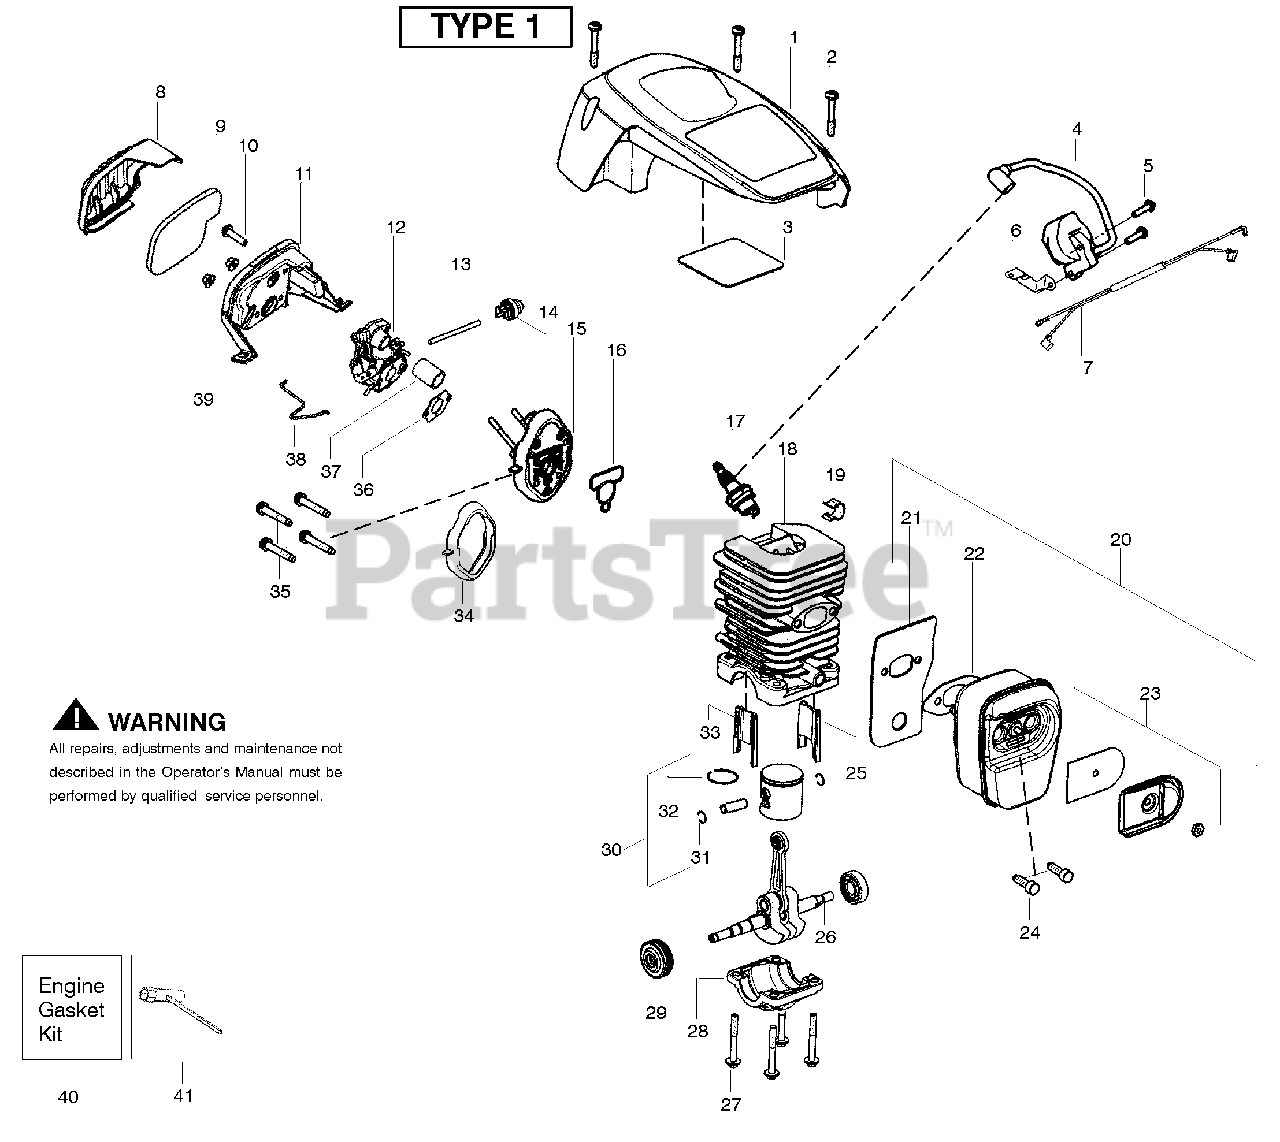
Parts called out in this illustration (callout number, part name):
1	Shield-Cylinder
3	Reflector-Tape
4	Module-Ignition Walbro EPS
6	Strap-Ground
7	Assy-Wire Harness
8	Cover-Air Filter
9	Filter-Air
11	Housing-Air Filter
12	Carburetor Zama X830
12	Carburetor Walbro WX5672
13	Kit-Fuel Line (Small)
14	Bulb-Purge "snap-in"
15	Kit-Carb. Adaptor
16	Gasket-cyl. o-ring (kit)
17	Accy-Spark Plug (RCJ-7Y)
18	Kit-Cylinder
19	Clip-High Tension Lead
20	Kit-Muffler
21	Backplate-Muffler
22	Gasket-Muffler (kit)
23	Kit-Spark Arrestor
24	Bolt-Muffler
25	Insert-Left (black) Cyl.
26	Assy-Crankshaft/Rod
28	Cap-Crankcase
29	Assy-Bearing/Seal
30	Kit-Piston
31	Retainer-Piston Pin
32	Ring-Piston
33	Insert-Right (gray) Cyl.
34	Seal-Adaptor (kit)
36	Gasket-Carb. (kit)
37	Tube-Intake
38	Wire-Throttle
39	Nut-Carb.
40	Kit-Gasket
41	Wrench-Bar
